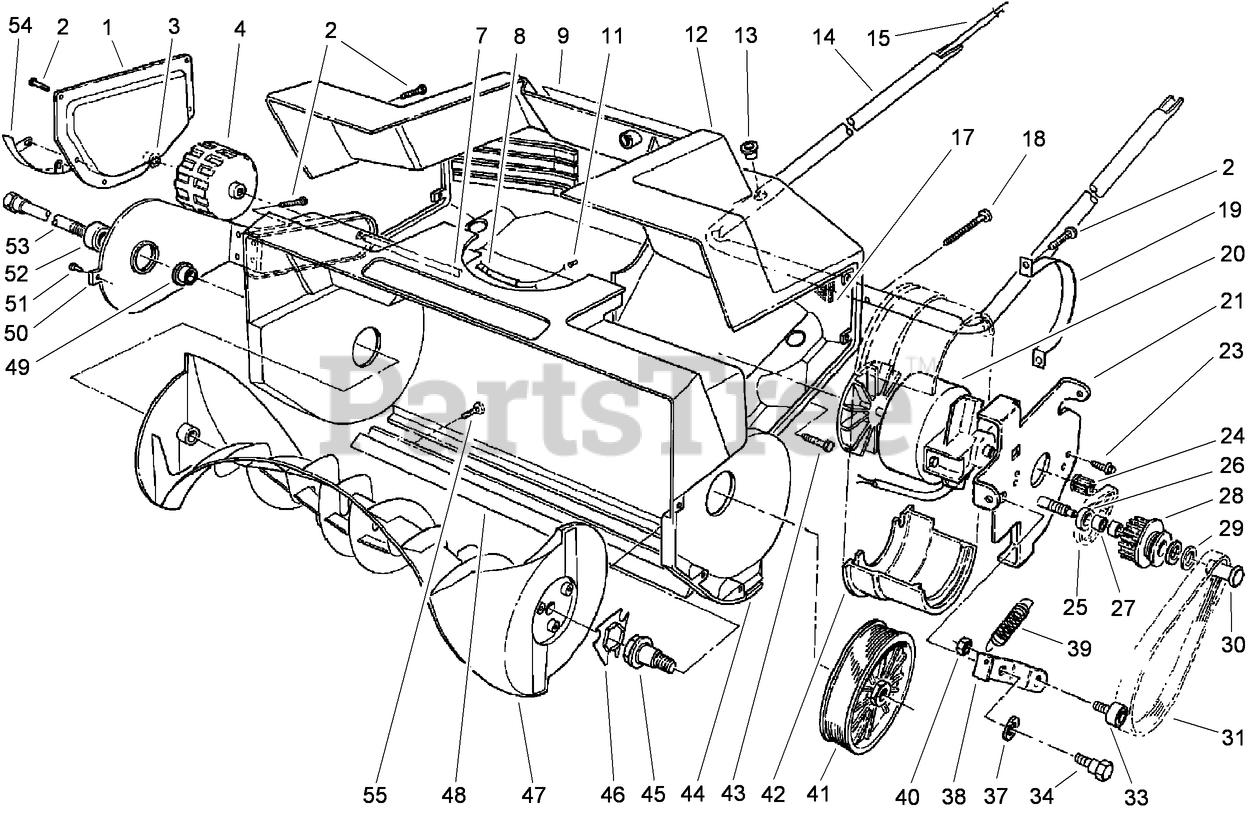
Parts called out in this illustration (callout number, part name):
2	SCREW-PPH
3	PUSHNUT-CAP, WASHER
4	WHEEL, 1200/1800
7	AXLE SHAFT
8	STRAIN RELIEF-GRIPMASTR
11	CONNECTOR SCREW
12	SHROUD - 1800 P.C.
13	BUSHING
17	FOAM FILTER
18	SCREW-PLASTIC, PPH
19	STRAP-MOTOR, FINISHED
20	MOTOR, 1800
21	PLATE - MOTOR ASSY.
23	TEKS SCREW
24	DRIVER PULLEY
25	BELT-PULLEY, IDLER/DRIVER
26	WASHER
27	Bearing-Needle
29	WASHER-THRUST
30	IDLER BOLT
33	IDLER BEARING
34	SCREW-SHOULDER
37	WASHER
38	IDLER BRACKET
39	IDLER SPRING
40	NUT-LOCK, NI
41	DRIVEN PULLEY
42	1800 CLAMP MTR BRCKT
43	SCREW-HWH THD CUT
44	ROTOR/HOUSING 1800
45	SHAFT, ROTOR DRIVE
46	COUPLER, ROTOR
47	ROTOR - 1800 SNOWBLOWER
48	SCRAPER - 1800
49	BUSHING
50	Bracket-Wheel (Incl. Ref. #52)
51	RIVET-POP
54	SKID, 1800
